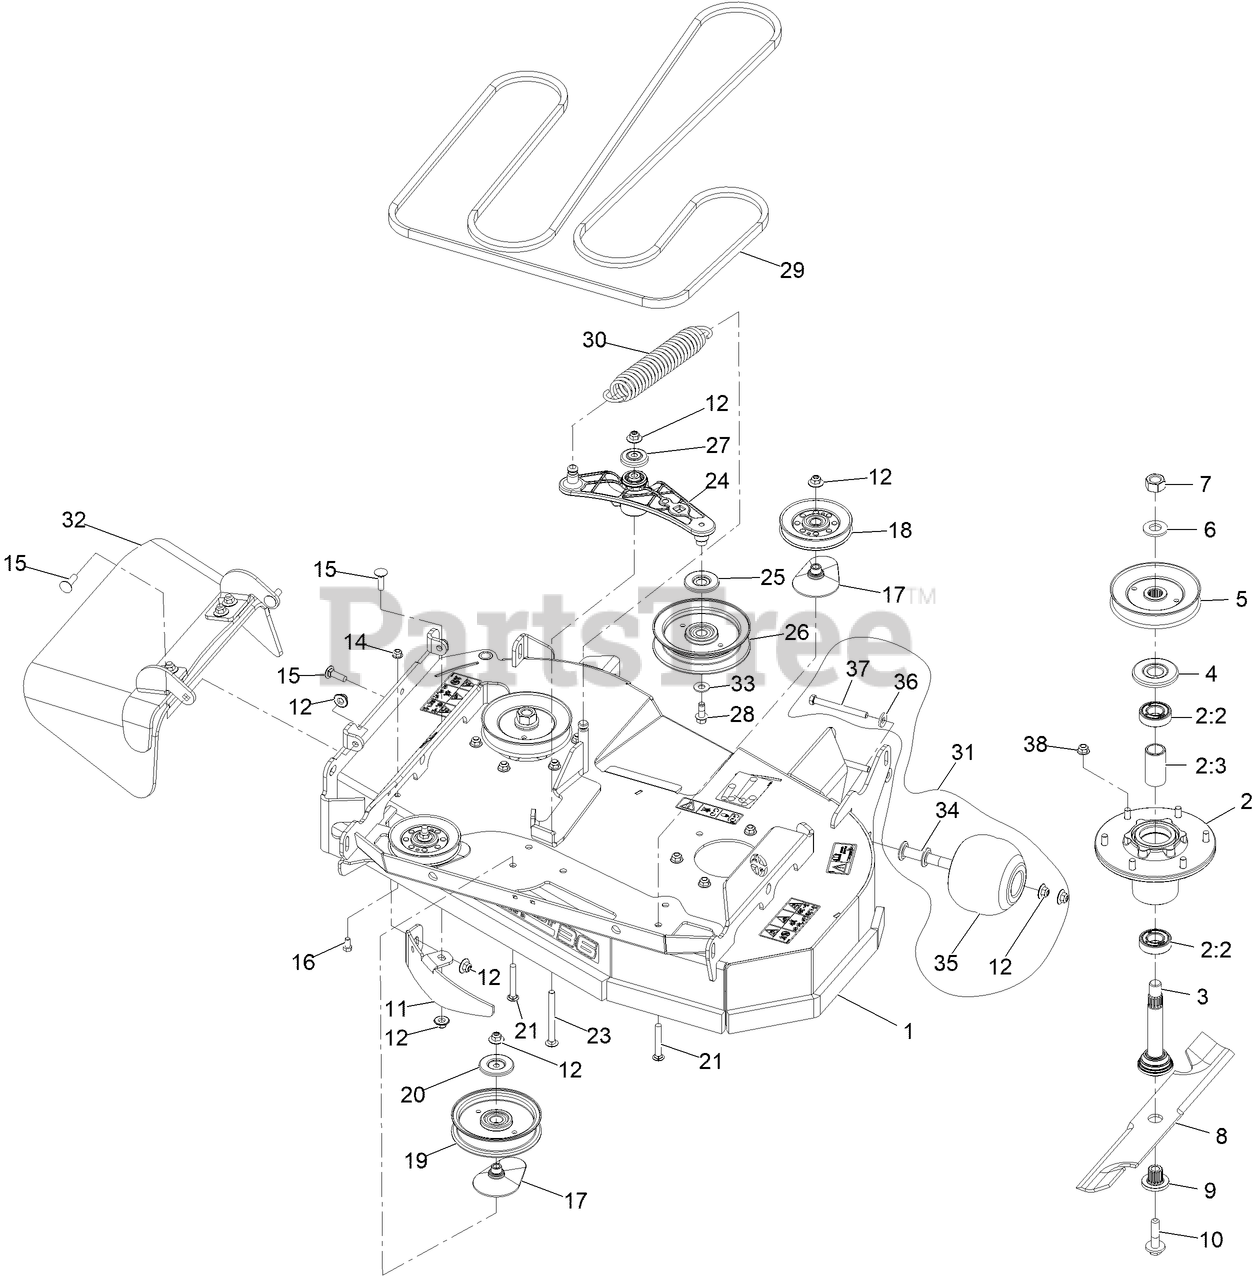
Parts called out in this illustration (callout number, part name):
1	ASM, 36" DECK W/ DECALS
2	ASM-Cutter Hsg With Bearings
2:2	BEARING-BALL
2:3	SPACER-BEARING
3	ASM-SPINDLE AND SEAL
4	GUARD,BEARING TOP .989
5	SHEAVE-BLADE DRIVE
7	NUT-HEX
9	BUSHING,SPLINED
10	SCREW,SEMS 1/2-20 X 2.19
11	BAFFLE, DOGLEG
12	Nut-Nyloc 3/8-16 Flg
14	NUT-HF, NI
15	BOLT-CARR
16	SCREW-HH
17	SPACER-PULLEY
18	Idler - V 4.13 Eod-A
19	Pulley-Idler, Flat
20	SHIELD-DUST
21	SCREW-CARR
23	SCREW-CARR
24	ASM.-ARM, IDLER
25	SHIELD-GUARD, DUST
26	IDLER-PULLEY, FLAT
27	GUARD-TOP
28	SCREW-HFH
30	SPRING-EXTENSION
31	KIT, ANTI-SCALP ROLLER
32	RUBBER DEFLECTOR ASM
33	WASHER-FLAT
34	AXLE, ROLLER
35	ROLLER-SCALP, ANTI
36	WASHER-BELLEVILLE
37	SCREW-HH 3/8-16 X 3 3/4 GR 8
38	NUT-HF, NI
